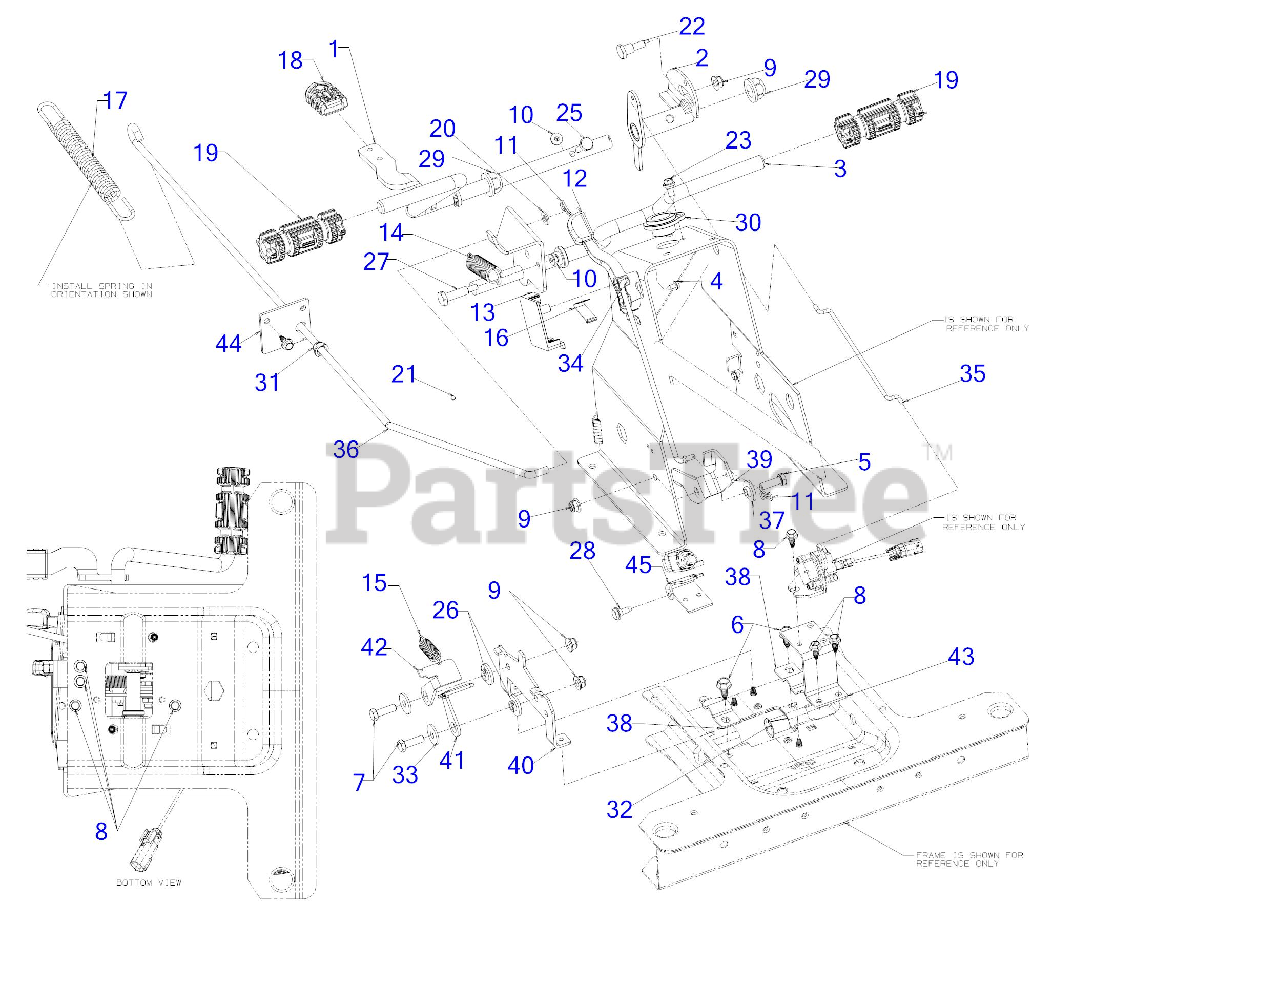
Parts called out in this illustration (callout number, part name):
2	PEDAL ASSEMBLY
4	HEX SCREW AB-TAP #10-16 x 0.500
5	SCREW 5/16-18 x 1.0 GR5
6	SCREW 5/16-18 x .750
7	SCREW 5/16-18 x 1.00 GR5
8	SCREW 1/4-20X.625
9	FLANGE LOCK NUT 5/16-18
10	FLANGE LOCK NUT
11	BOW TIE COTTER PIN 1/4-5/16
12	PARK BRAKE LEVER
13	SPEED CONTROL COVER
14	EXTENSION SPRING
15	EXTENSION SPRING
16	SHIFT SPRING
17	EXTENSION SPRING 0.90 DIA x 8.14
18	REVERSE PEDAL PAD
19	BRAKE PEDAL PAD
20	FLAT WASHER
22	SHOULDER SCREW 5/16-18 x .62 GR2
25	SHOULDER SCREW .375 x .148
26	SHOULDER SPACER .315 X .500 X .140
27	SHOULDER SCREW
28	SHOULDER SCREW
29	FLANGE BEARING
30	FLANGE BEARING
31	BUSHING .380 ID
32	FLANGE BEARING .626 x .938 x .875
33	THRUST BEARING .323 X .985 X .100
34	SPEED SELECT ROD
35	SWITCH ROD
37	SHOULDER SPACER
38	BRAKE SHAFT STRAP
39	PARK BRAKE BRACKET
41	REVERSE RETURN BRACKET
42	FORWARD RETURN BRACKET
